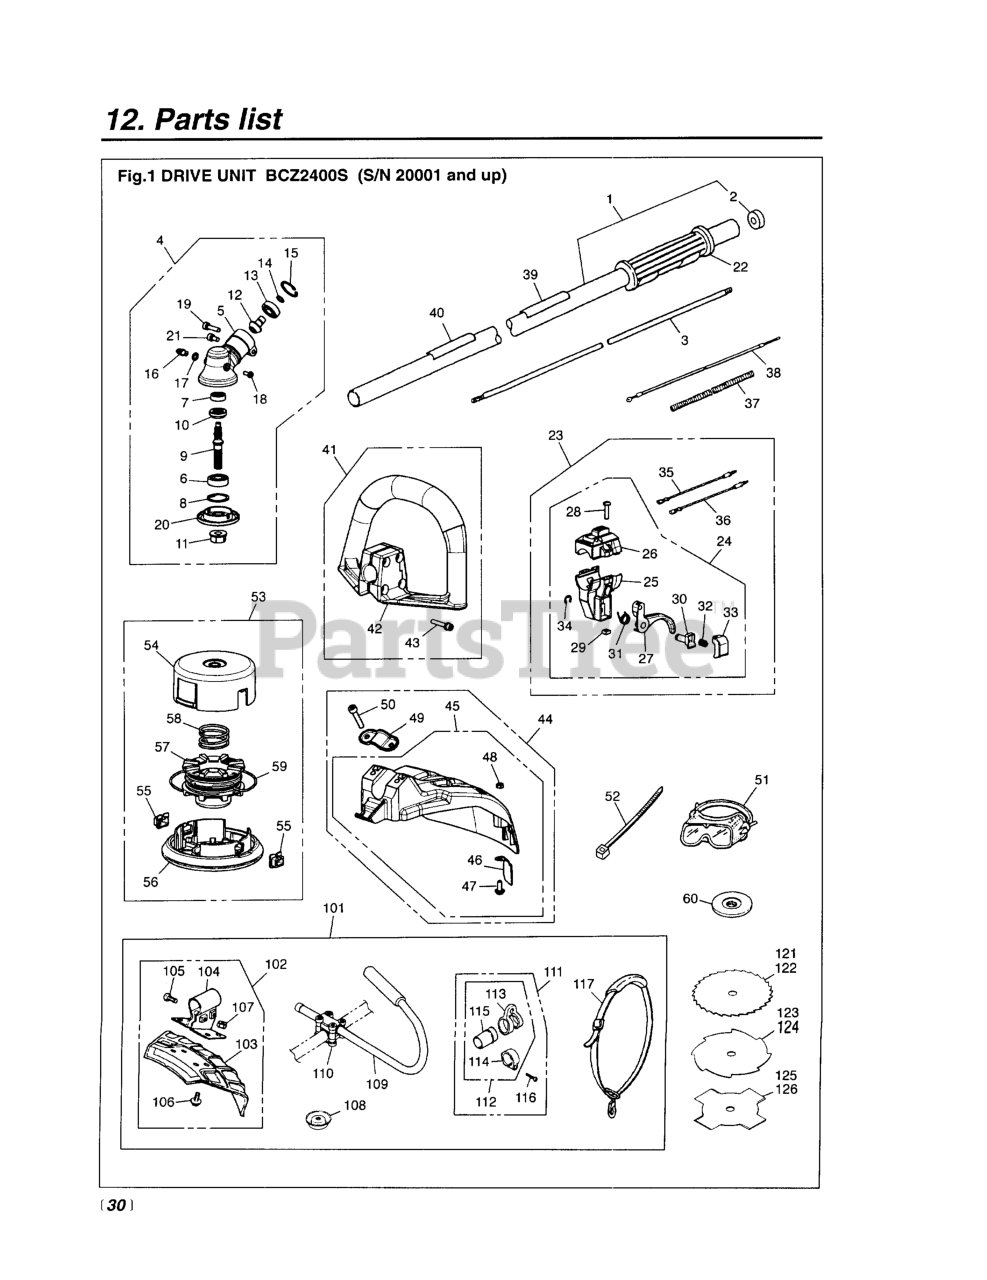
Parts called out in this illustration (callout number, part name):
1	PIPE COMP
2	SEAL
3	SHAFT (RPLS -12212)
4	GEARCASE ASSY.
5	GEARCASE
6	BEARING
7	BEARING (RPLS T3300-13521)
8	RING, SNAP, M26 X 1.2
9	SHAFT
10	GEAR
11	NUT
12	PINION
13	BEARING (RPLS T3300-13531)
14	RING, SNAP (RPLS T3300-13330)
15	RING, SNAP, M24 x 1.2
16	FITTING, GREASE
17	WASHER, M6 X .8
19	BOLT (RPLS 2850-14220)
20	HOLDER (A)
21	BOLT
22	GRIP (RPLS 3577-32140 & 3220-
24	LEVER (USE 848-8R2-0313)
26	COVER (USE 848-8RA-0340)
27	FLEX, TRIGGER
35	CORD (A), BLACK
36	CORD (B), RED
37	TUBE
38	CABLE COMP (RPLS 1633-83100)
39	PLATE, NAME
40	PLATE, CAUTION
41	HANDLE ASSY. (REPLACES -14001)
42	HANDLE T
43	SCREW
44	GUARD ASSY. (RPLS -24002)
45	GUARD COMP.
46	BLADE (RPLS T3002-24120)
47	SCREW TORX
48	NUT
49	CLAMP (REPLACES 5807-24120)
50	BOLT, TORX
51	GOGGLE
53	4
54	CASE (REPLACES -15111)
55	EYELET
56	COVER (REPLACES -15131)
57	HOLDER, CORD (REPLACES-15141)
58	SPRING
59	CORD
60	HOLDER (B)
101	BLADE KIT (BC00090)
102	GUARD ASSY.
103	GUARD (ACC.)
105	BOLT
106	SCREW
107	NUT, M6 X 5
108	COVER
109	HANDLE, J
110	BRACKET ASSY (REPLACES -14100)
111	HANGER ASSEMBLY
112	HANGER COMPLETE
113	HANGER
114	CLAMP
115	SLEEVE
116	SCREW, M5 x 25
117	STRAP ASSY.
121	BLADE, 9
122	BLADE, 9
123	BLADE, 8
124	BLADE, 9
125	BLADE, 8
126	BLADE, 9
